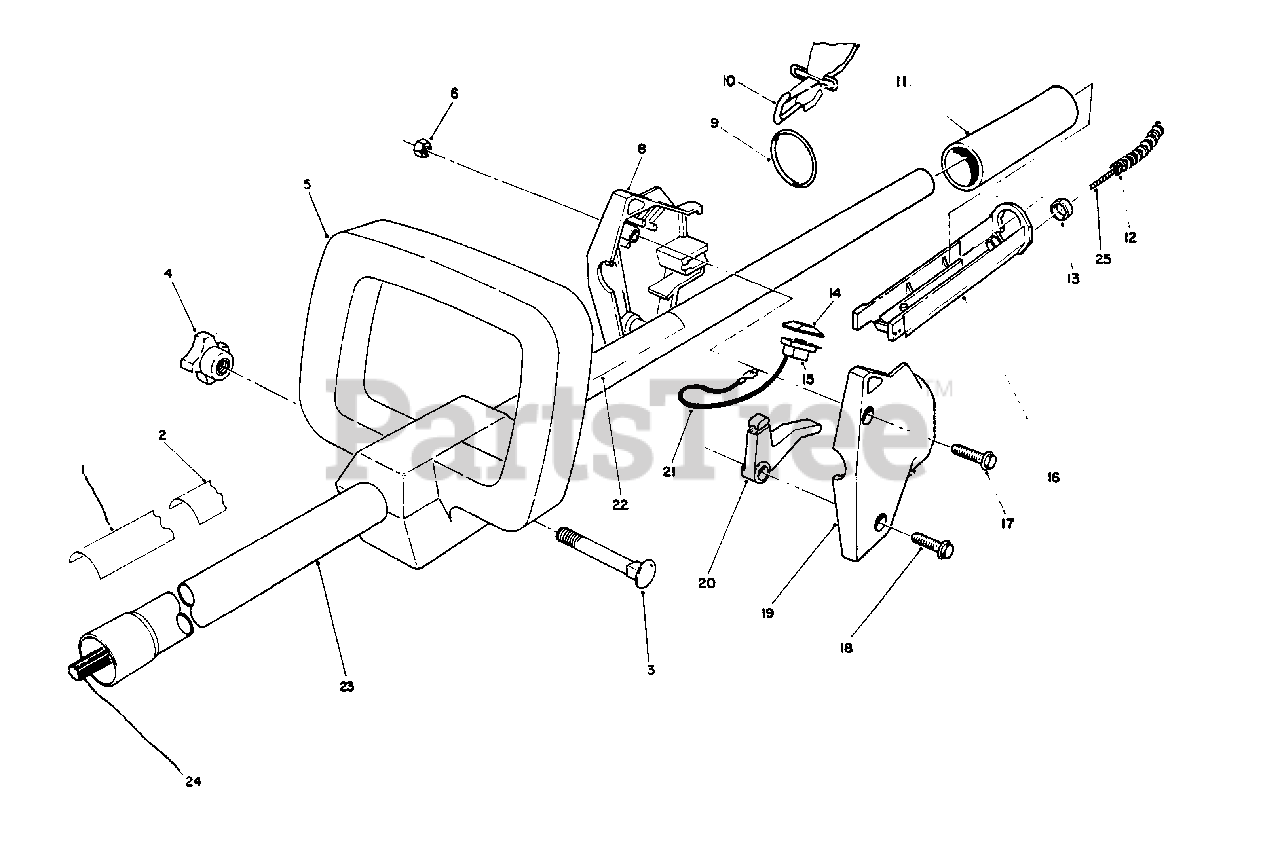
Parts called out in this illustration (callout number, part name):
1	Decal-TC 3110
2	Decal-Instructions
3	Bolt Carriage
4	Knob
5	Handle-Secondary
6	Nut-Lock
8	Housing Assembly R.H.
9	Ring-Harness
10	Harness-Shoulder
11	Grip-Drive Housing
12	Cover-Cable
14	Cap-Switch
17	Screw-Hex. Hd. Cap
18	Screw-Hex. Hd. Cap
19	Housing Assembly-L.H.
20	Lever-Throttle
21	Wire Assembly
22	Decal-Danger
23	Tube Assembly
24	Saft-Spline, Drive
25	Cable-Throttle
